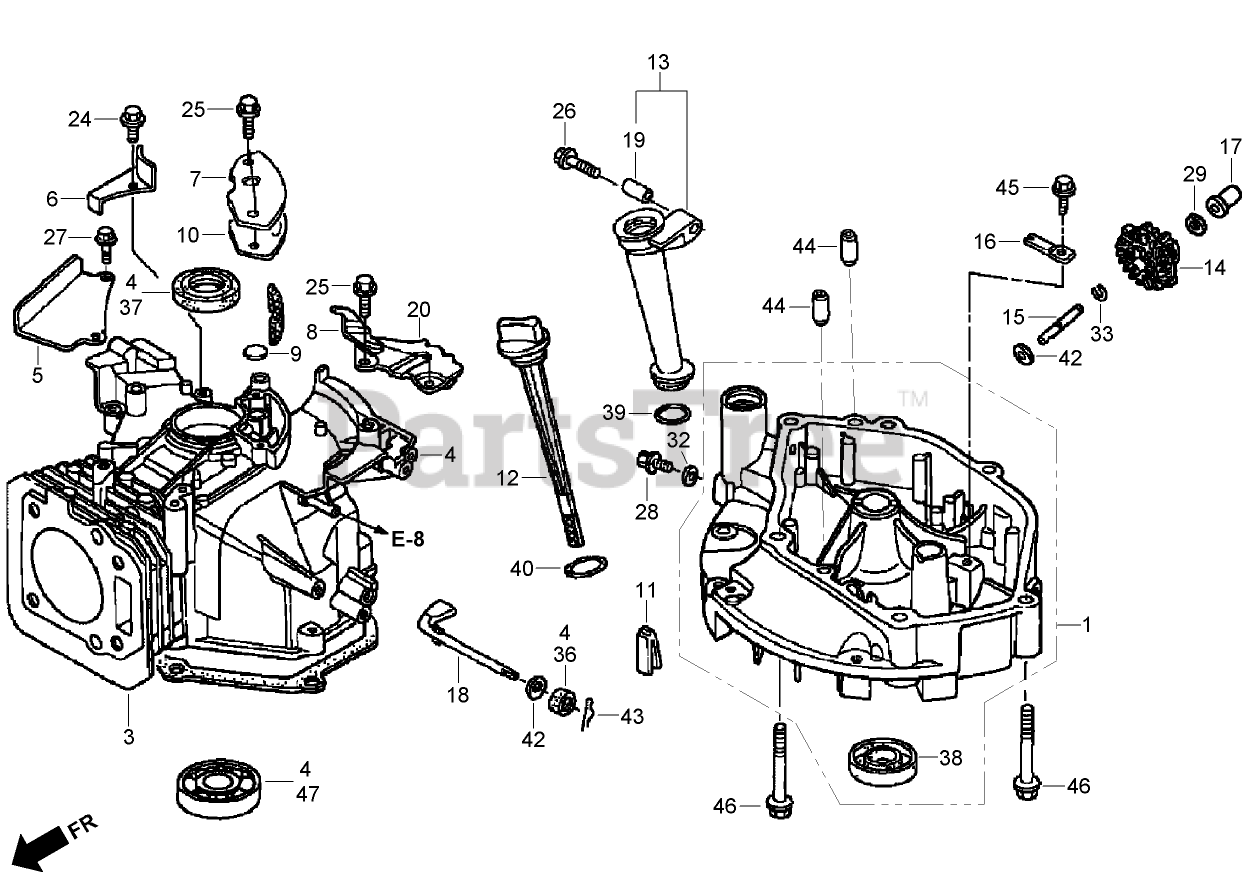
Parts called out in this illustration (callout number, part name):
1	OIL PAN ASM
3	GASKET-PAN, OIL
4	CYLINDER ASM
5	PLATE-GUIDE
6	PLATE-GUIDE (A)
7	COVER-BREATHER
8	Filter-Breather
9	VALVE-BREATHER
10	GASKET-COVER, BREATHER
11	RUBBER-RETURN, OIL
12	Dipstick-Oil
13	EXTENSION-FILLER, OIL (106 mm)
14	GOVERNOR ASM
15	SHAFT-HOLDER, GOVERNOR
16	Plate-HOLDER, Governor Shaft
17	SLIDER-GOVERNOR
18	SHAFT-ARM, GOVERNOR
19	Collar-Extension
20	STAY-TANK
24	BOLT-FLANGE (6X12) (C T200)
25	BOLT-FLANGE (6X14) (C T200)
26	Bolt-Flange (6X32)
27	BOLT-FLANGE (6X20) (C T200) (engine serial numbers up to 6702082)
28	Bolt-PLUG, Drain
29	WASHER-THRUST (6MM)
32	WASHER-PLUG, DRAIN (102MM)
33	CLIP-HOLDER, GOVERNOR
36	SEAL-OIL (6X11X4)
37	SEAL-OIL (25X38X7)
38	SEAL-OIL (25.4X40X7)
39	O-RING (22.1X2.2)
40	O-RING (25.5X3)
42	WASHER-PLAIN (6MM)
43	PIN-LOCK (8MM)
44	Pin-Dowel (8X14)
45	Bolt-Flange (6X12)
46	BOLT-FLANGE (8X50)
47	BEARING-BALL, RADIAL (6205)
